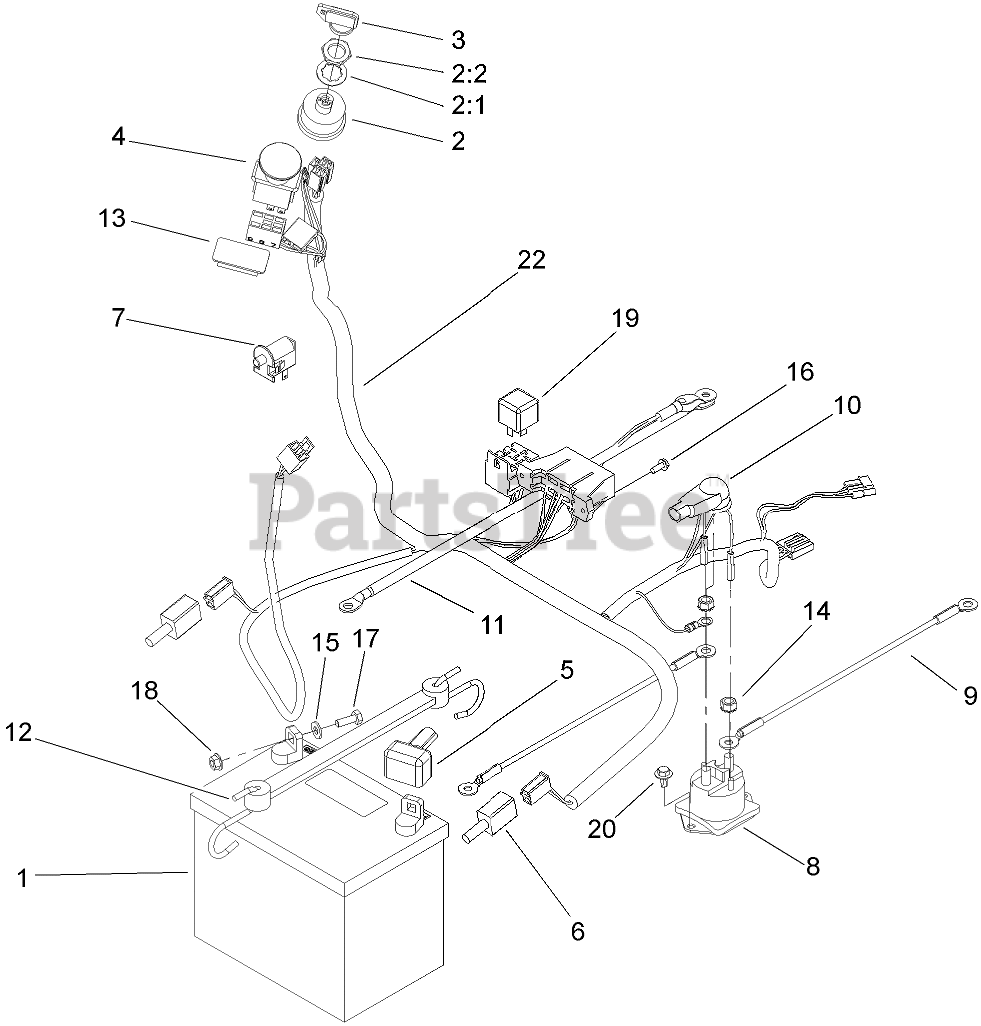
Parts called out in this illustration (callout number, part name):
1	BATTERY
2	Key Switch ASM
2:1	WASHER-TOOTH, INTERNAL
2:2	NUT-HH
3	KEY-IGNITION
4	SWITCH-PTO
5	BOOT-TERMINAL
6	SWITCH
7	SWITCH-BAIL
8	SOLENOID-STARTER
9	WIRE ASM
10	BOOT-INSULATOR, TERMINAL
11	CABLE-NEGATIVE, BLACK
12	HOLDDOWN-BATTERY
13	PLUG-HOLE
14	NUT-KEPS
15	WASHER-FLAT
16	SCREW-TAPTITE
17	SCREW-HH
18	NUT-HF
19	RELAY
20	SCREW-HHFTF
22	HARNESS-WIRING
